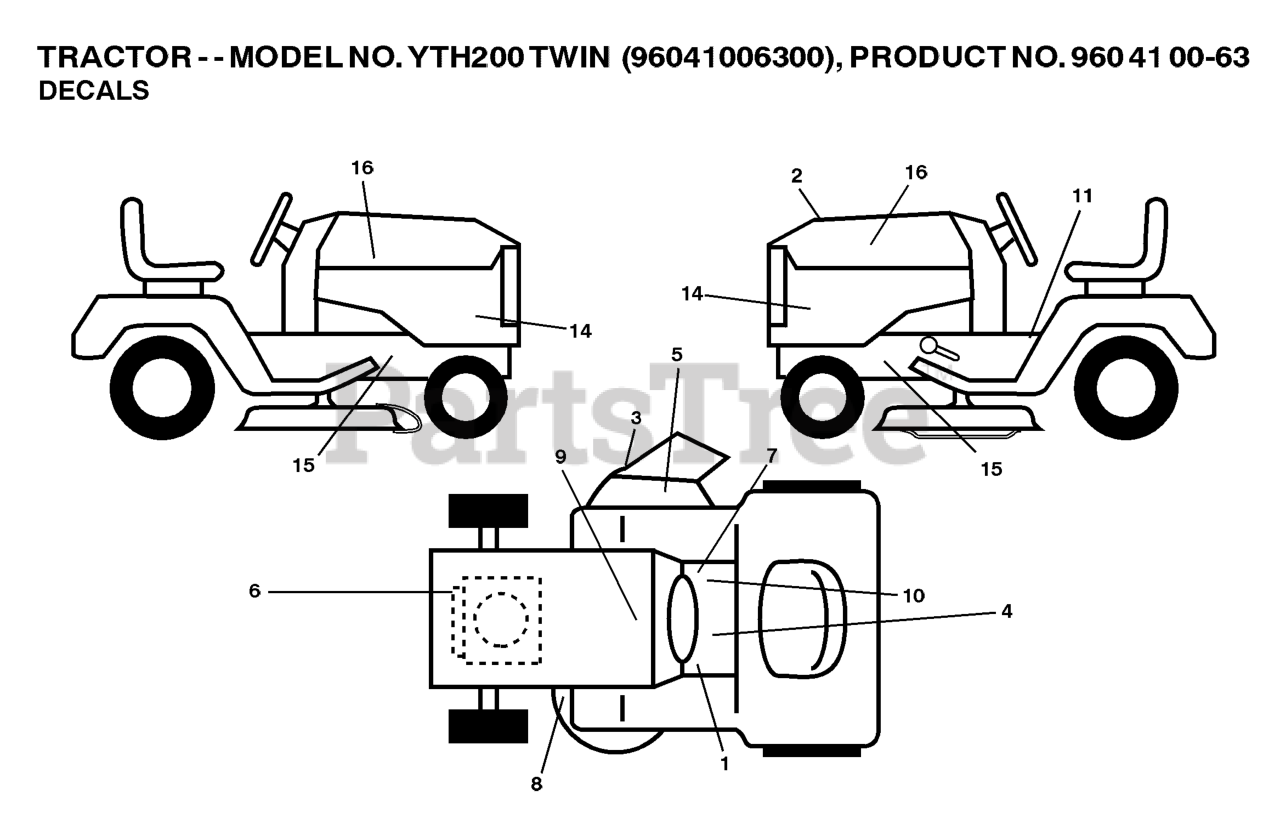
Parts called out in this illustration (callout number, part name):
1	LABEL
3	DECAL, DEFLECT WARNING
4	DECAL
5	DECAL PARK BRAKE
6	DECAL
8	DECAL V BELT SCHEMATIC
9	DECAL BTRY SYMBOLS
10	DECAL
12	DECAL.INTERNATIONL.CUTFINGER
15	Decal, Fender 100 DB/CE
16	DECAL.HOOD.NAMELOGO.HUSQ
